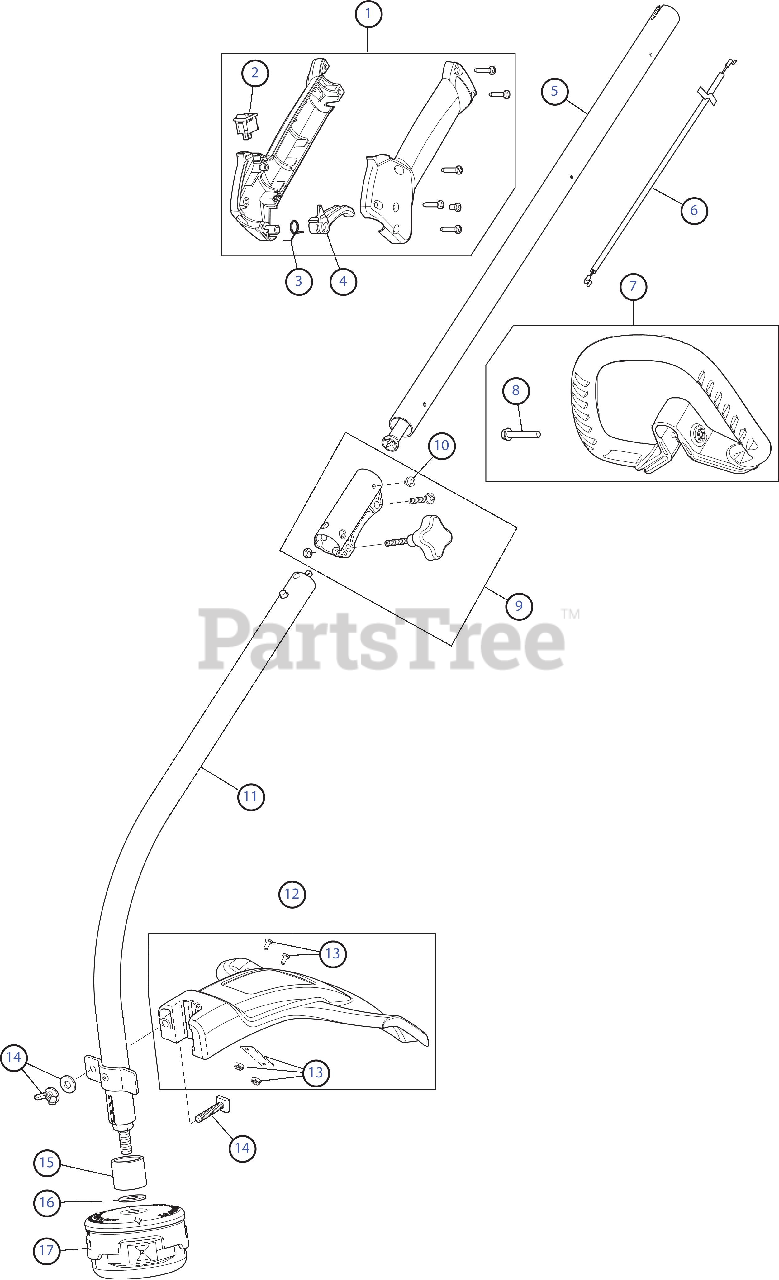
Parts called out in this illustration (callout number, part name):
1	Throttle Housing Assembly (Incl. 2 - 4)
2	Switch Assembly
3	Throttle Trigger Spring
4	Throttle Trigger
5	Upper Drive Shaft Housing Assembly
6	Throttle Cable Assembly
7	D-Handle Assembly (Incl. 8)
9	Split Boom Coupler (Incl. 10)
11	Lower Drive Shaft Housing Assembly
12	Shield Assembly (Incl. 13)
13	Blade Assembly
14	Shield Mounting Hardware
16	Washer
17	Bump Head Assembly
